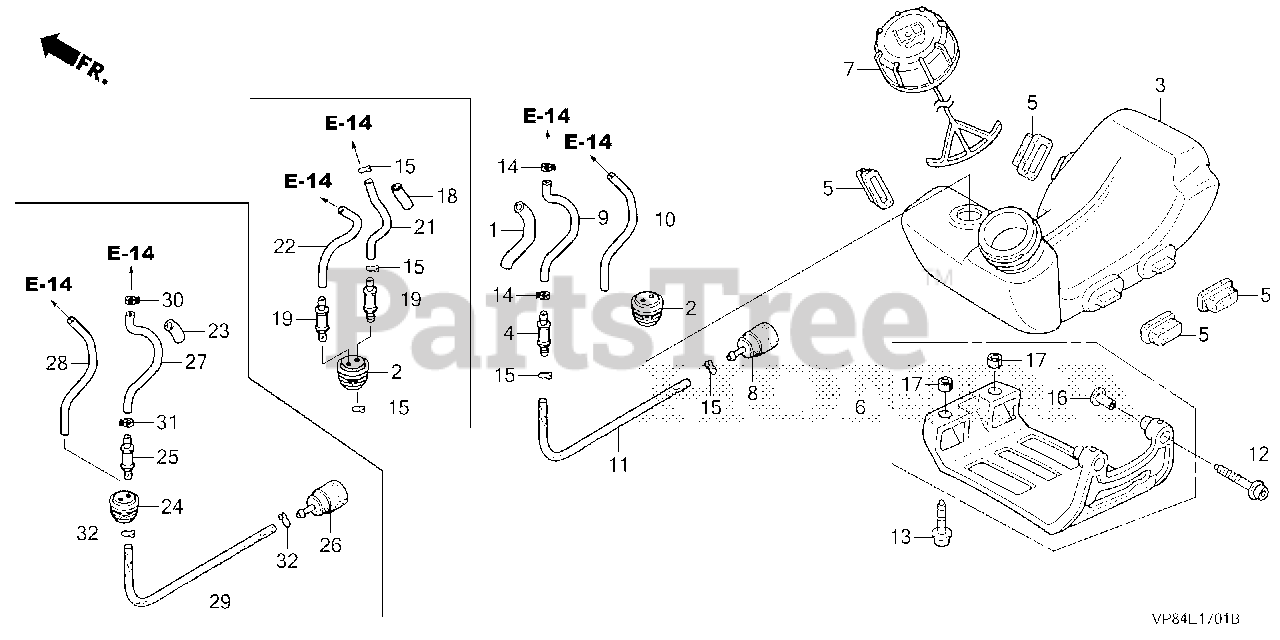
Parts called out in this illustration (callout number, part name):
3	TANK, FUEL
5	RUBBER, TANK MOUNTING
6	GUARD, TANK
7	CAP ASSY., FUEL TANK
12	BOLT, SOCKET (5X30)
13	BOLT, SOCKET (5X16)
16	COLLAR, TANK GUARD
17	COLLAR A, HEAD COVER
23	PROTECTOR, TUBE
24	GROMMET, FUEL TUBE
25	JOINT, FUEL TANK
26	FILTER, FUEL
27	TUBE, FUEL (FKM)
28	TUBE, FUEL RETURN
29	TUBE A, FUEL
30	CLAMP, TUBE (D5.5)
31	CLAMP, TUBE (D5.5)
32	CLIP, TUBE (B1 5)
